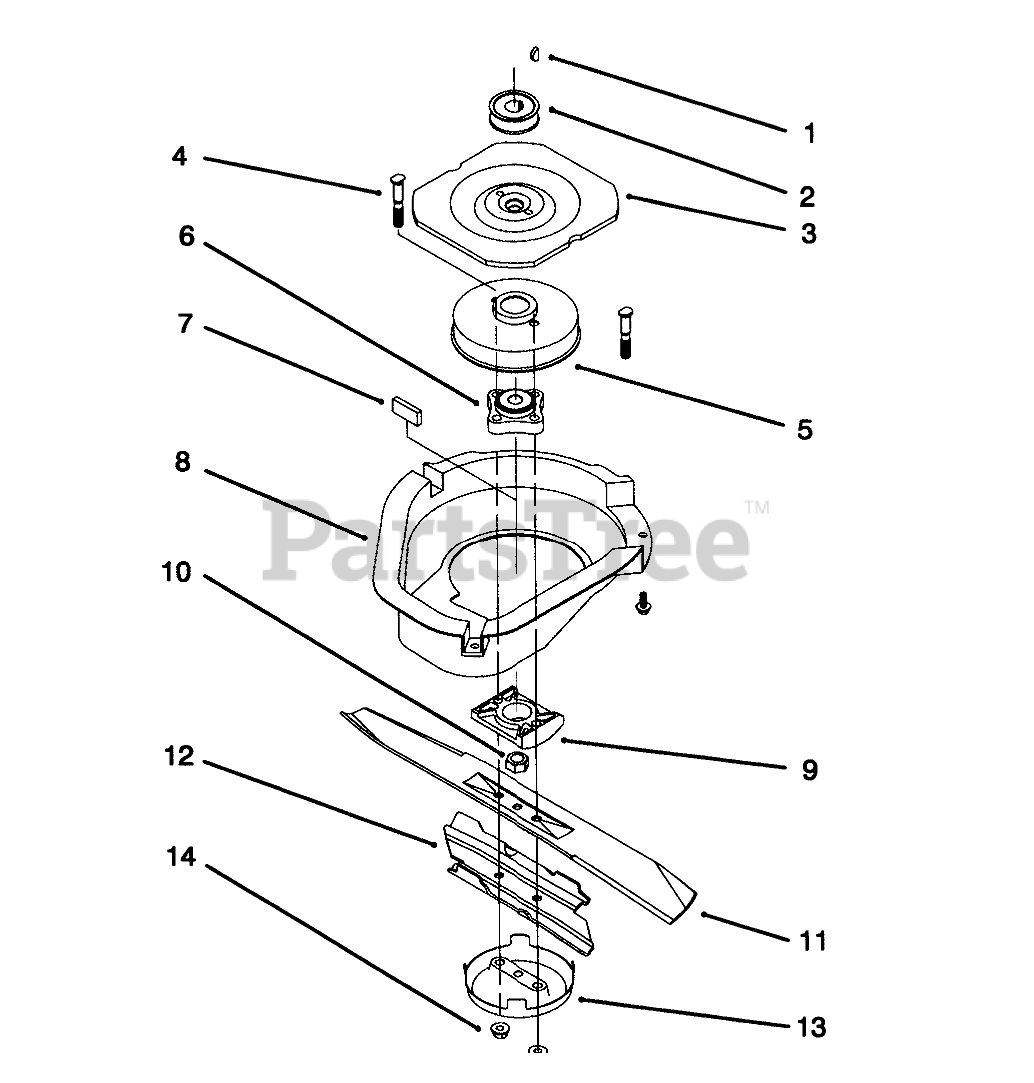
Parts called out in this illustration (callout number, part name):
1	KEY-WOODRUFF
2	PULLEY
3	Flywheel
4	BOLT-BLADE
5	Drum-Brake
6	HUB ASM
7	DAMPENER-VIBRATION
8	SHIELD BBC
9	SPACER - BLADE
10	NUT-LOCK, NI
11	Blade
12	Stiffener-Blade
13	CUP-SCALP, ANTI
14	NUT-LOCK
